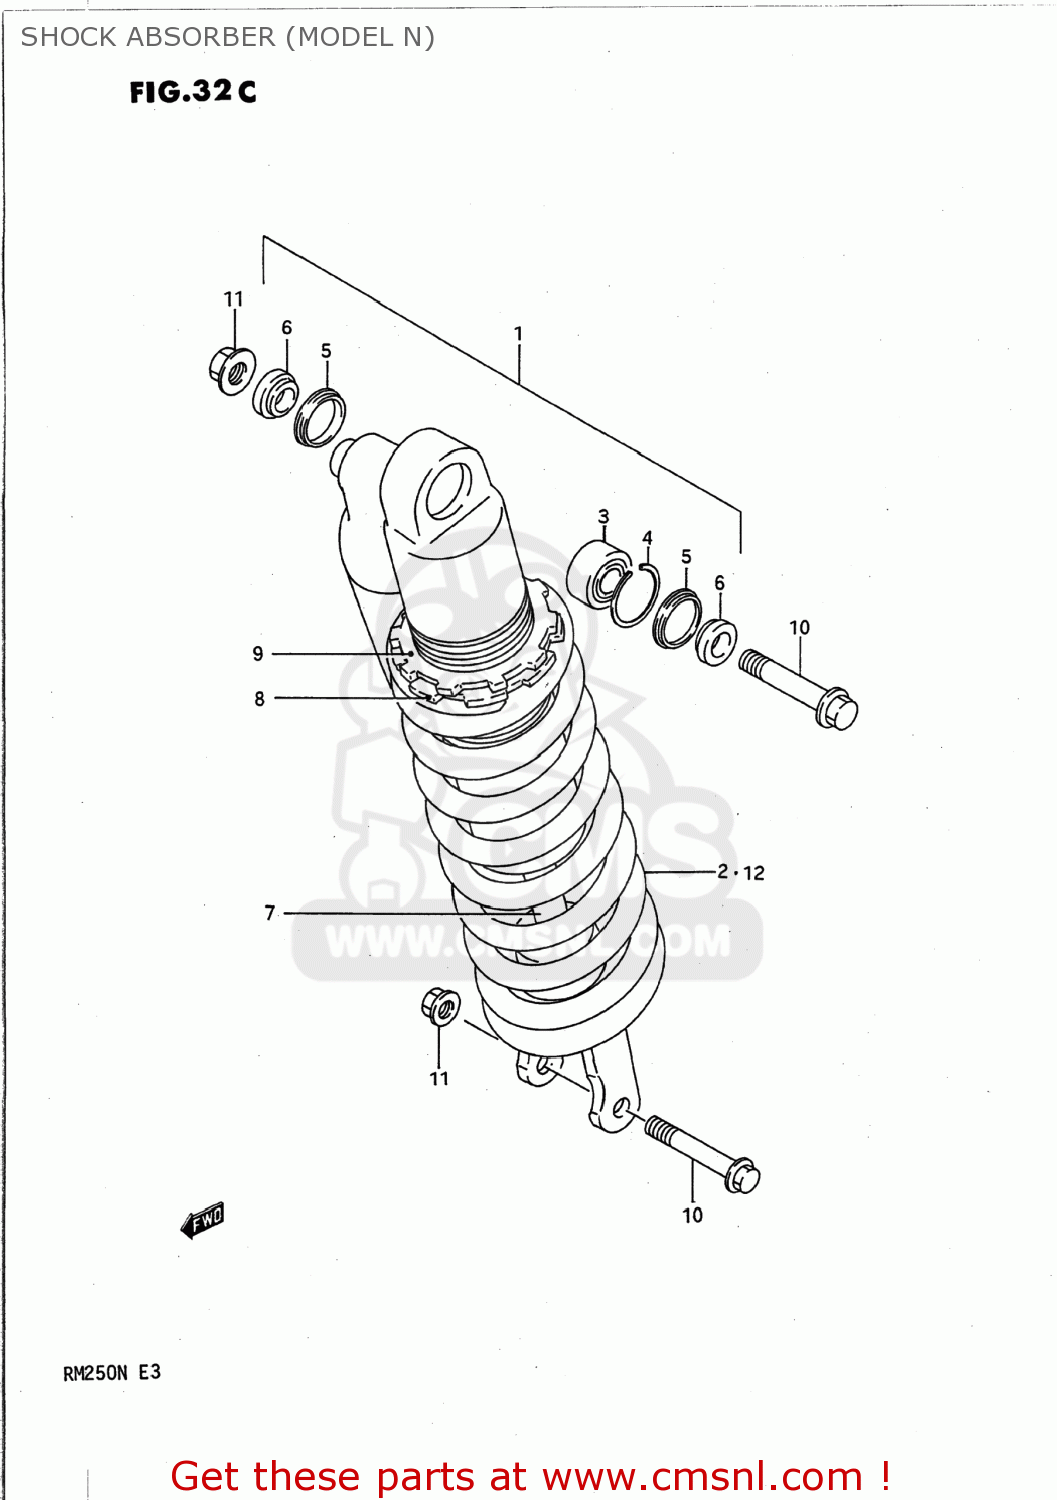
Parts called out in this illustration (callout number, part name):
1	ABSORBER ASSEMBLY,REAR SHOCK
2	SPRING
3	BEARING,REAR SHOCK ABSORBER
4	RING,STOPPER
5	SEAL,DUST
6	COLLAR
7	ROD,PISTON
8	GUIDE,SPRING
9	NUT
10	BOLT,REAR SHOCK ABSORBER
11	NUT
12	SPRING,REAR (K=5.4)
